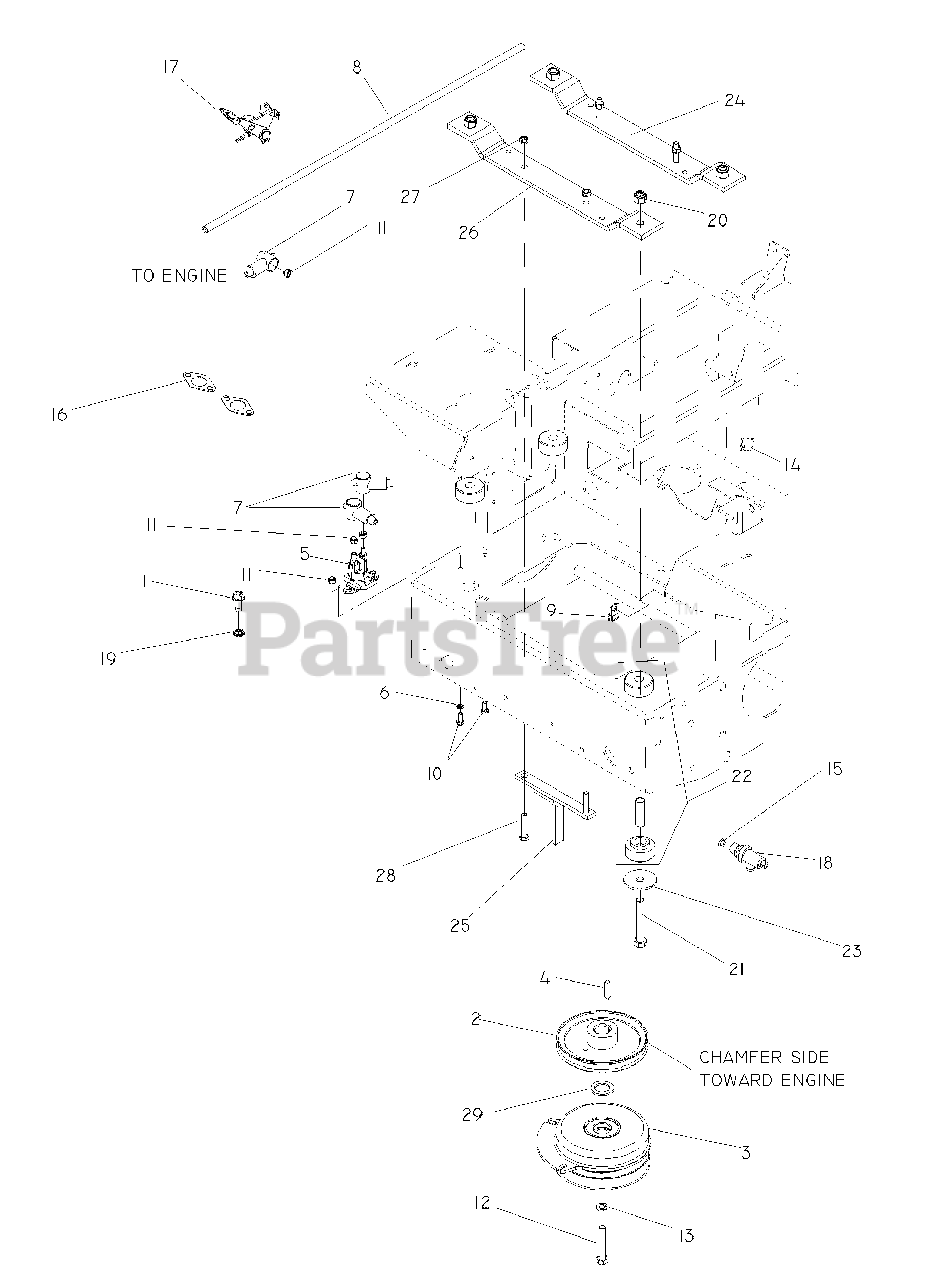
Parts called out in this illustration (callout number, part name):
1	BOLT 3/8-16 X 1.0
3	CLUTCH-200 FT LB(RPLS 5218-102
4	KEY, 1/4 SQ X 1 1/4
5	SOLENOID
6	WASHER 1/4 INT TOOTH
7	INSULATOR
8	FUEL LINE 29.5"
9	DOUBLE TUBE CLAMP
10	HCS 1/4C X 5/8
11	NUT 1/4-20 NYLOC
12	BOLT 7/16F X 2 1/2
13	WASHER 7/16 LOCK
14	TIE, PLASTIC
16	EXHAUST GASKET - KAW
17	CABLE CHOKE
18	VALVE ASSEMBLY
19	WASHER 3/8 EXT STAR ZD
20	NUT 1/2-13 HEX NYLOC ZD
21	HCS 1/2C X 3 1/4
22	ISOLATORS
23	ISOLATOR WASHER
24	ENGINE MOUNT
25	CLUTCH TIE DOWN
26	STRAP, ISO, REAR
27	NUT 5/16C CENTERLOCK
28	HCS 5/16-18 X 1-3/4 SERATED
29	BUSHING, 10GA MACHINERY
